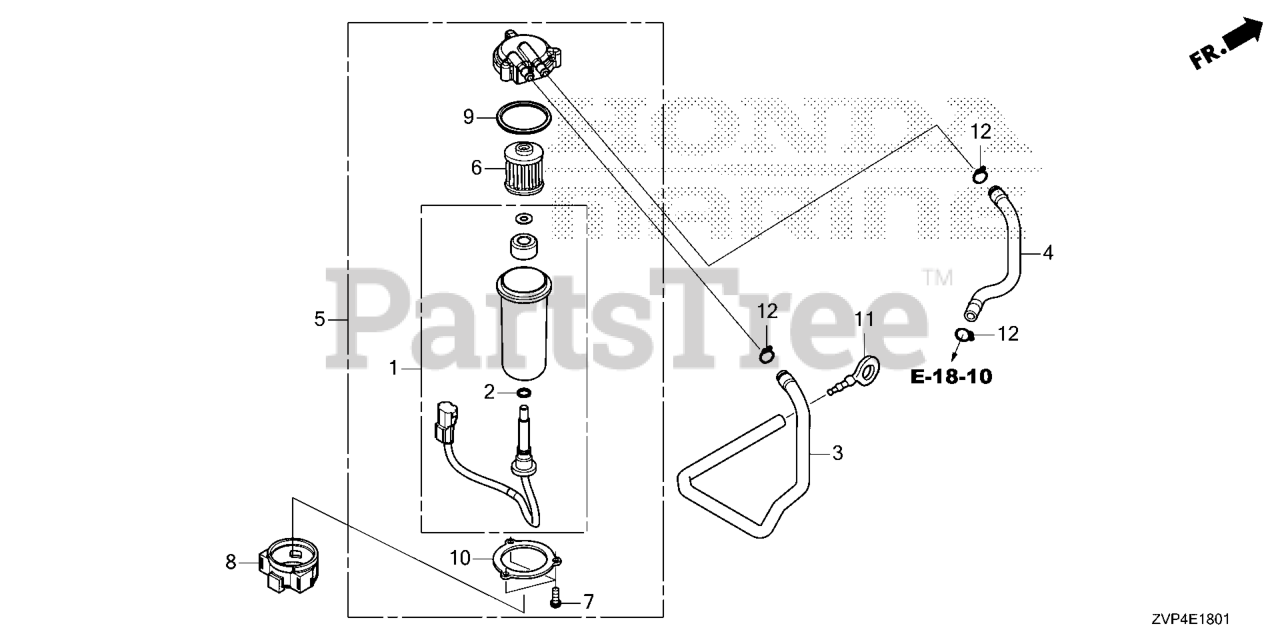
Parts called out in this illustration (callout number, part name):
1	CUP SET, WATER SEPARATOR
3	TUBE A, FUEL
4	TUBE B, FUEL
5	FILTER ASSY., FUEL (LOW)
6	FILTER, FUEL
7	SCREW, PAN (5X12)
8	SUSPENSION, STRAINER
11	PLUG, FUEL TUBE
12	CLIP, TUBE (B12)
